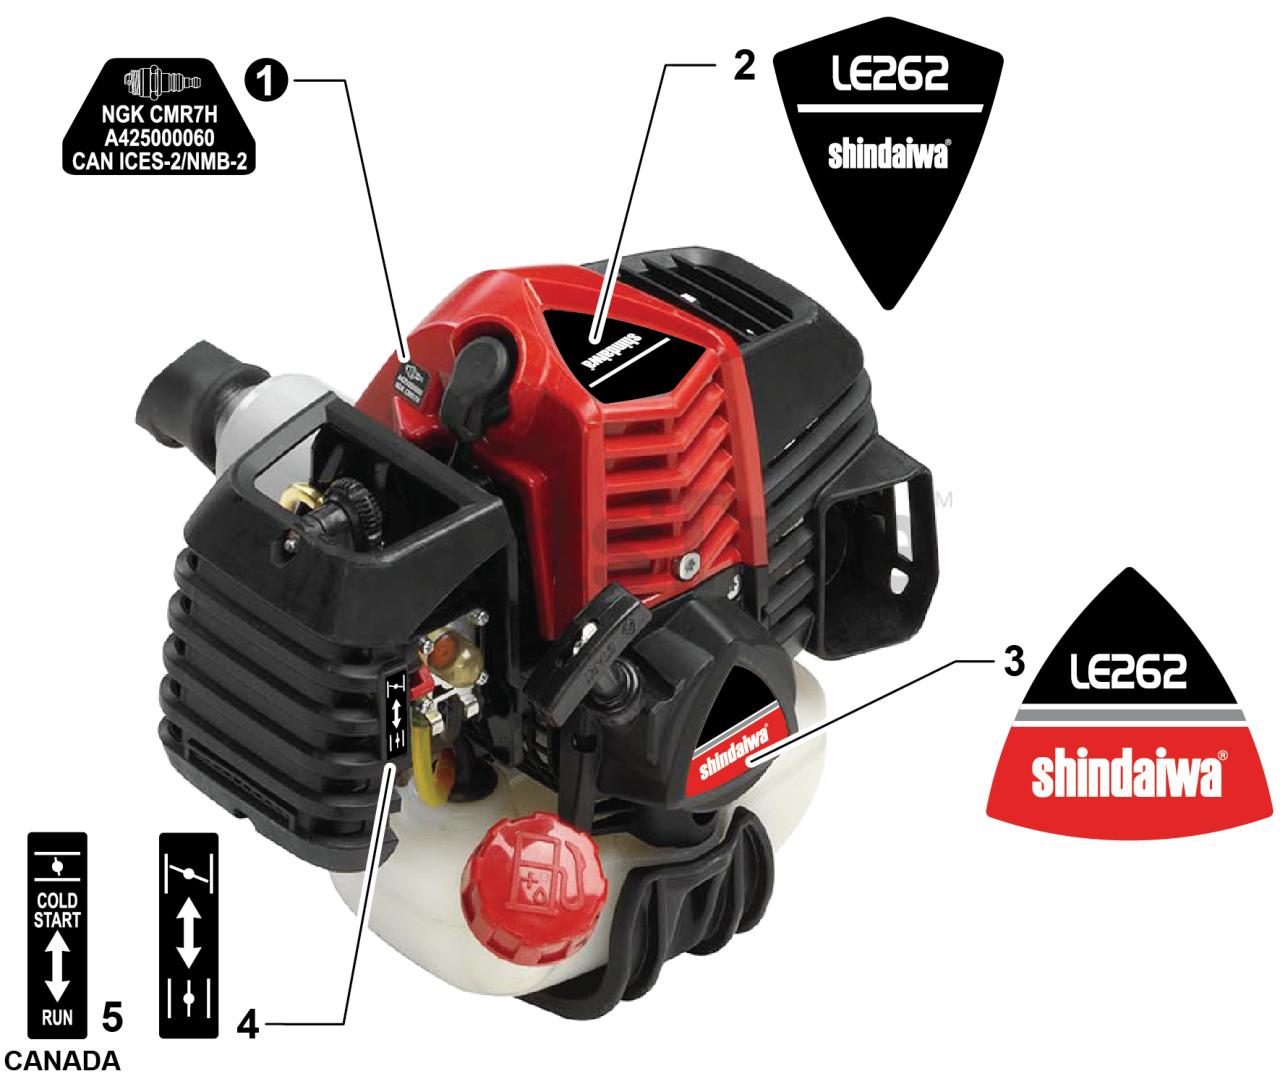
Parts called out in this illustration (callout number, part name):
1	LABEL - SPARK PLUG - CMR7H
2	LABEL - MODEL LE262
3	LABEL - RECOIL STARTER
4	LABEL - CHOKE
5	LABEL - CHOKE
